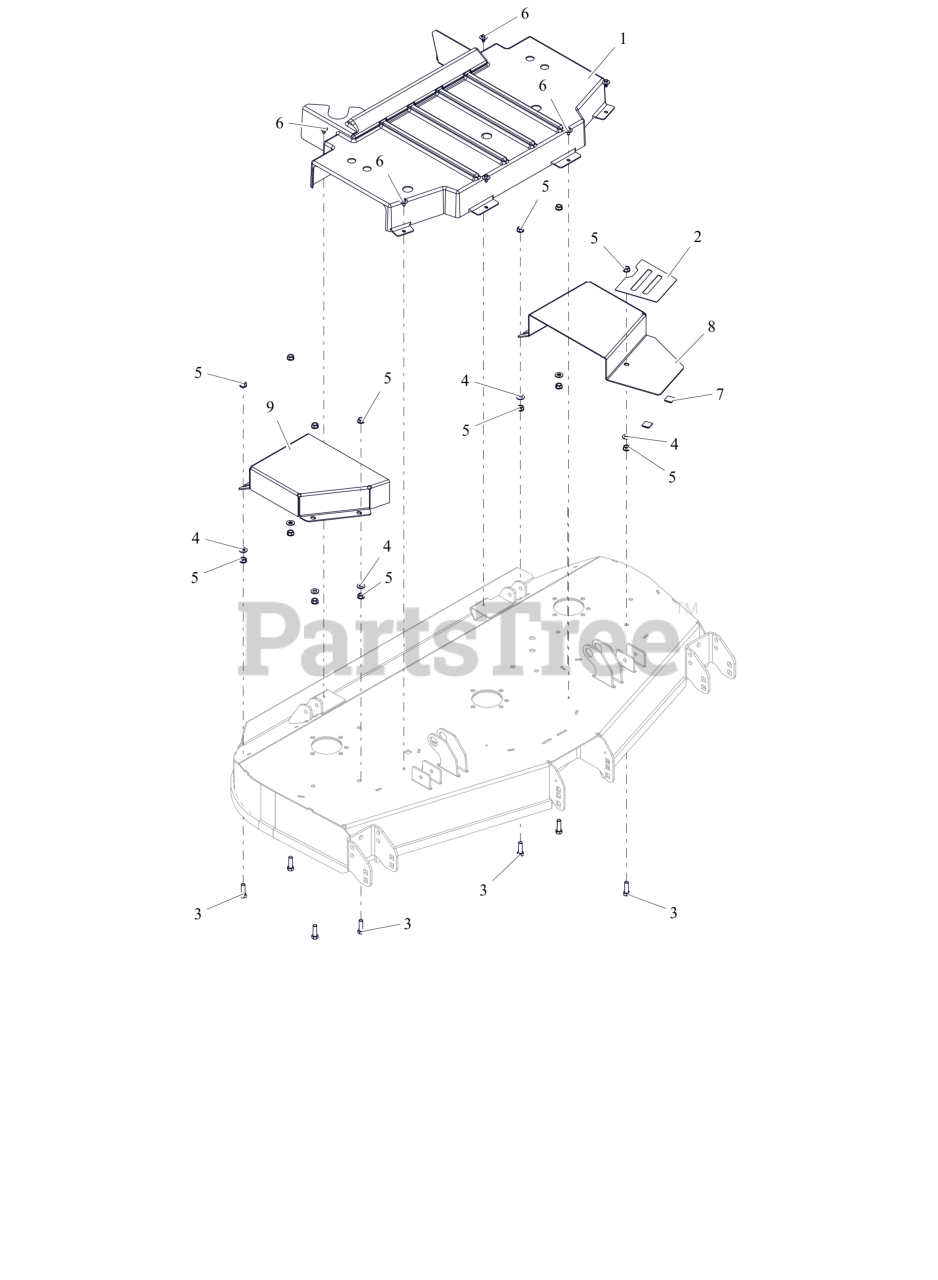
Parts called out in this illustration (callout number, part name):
1	GUARD,CENTER,DECK SPINDLE CE
2	GRIP TAPE 52-60 BELT COVER
3	BLT, HEX .38-16X1.25 G5 ZCC
4	WSHR,FLT .406X.812X.065 ZCC
5	NUT, SPNLK-FLG .38-16 G5 ZCC
6	SCR, TAP .25-20X.50 LG HWH ZCC
8	GUARD, BELT 52" LEFT
9	GUARD, BELT 52" RIGHT CE (ORANGE)
